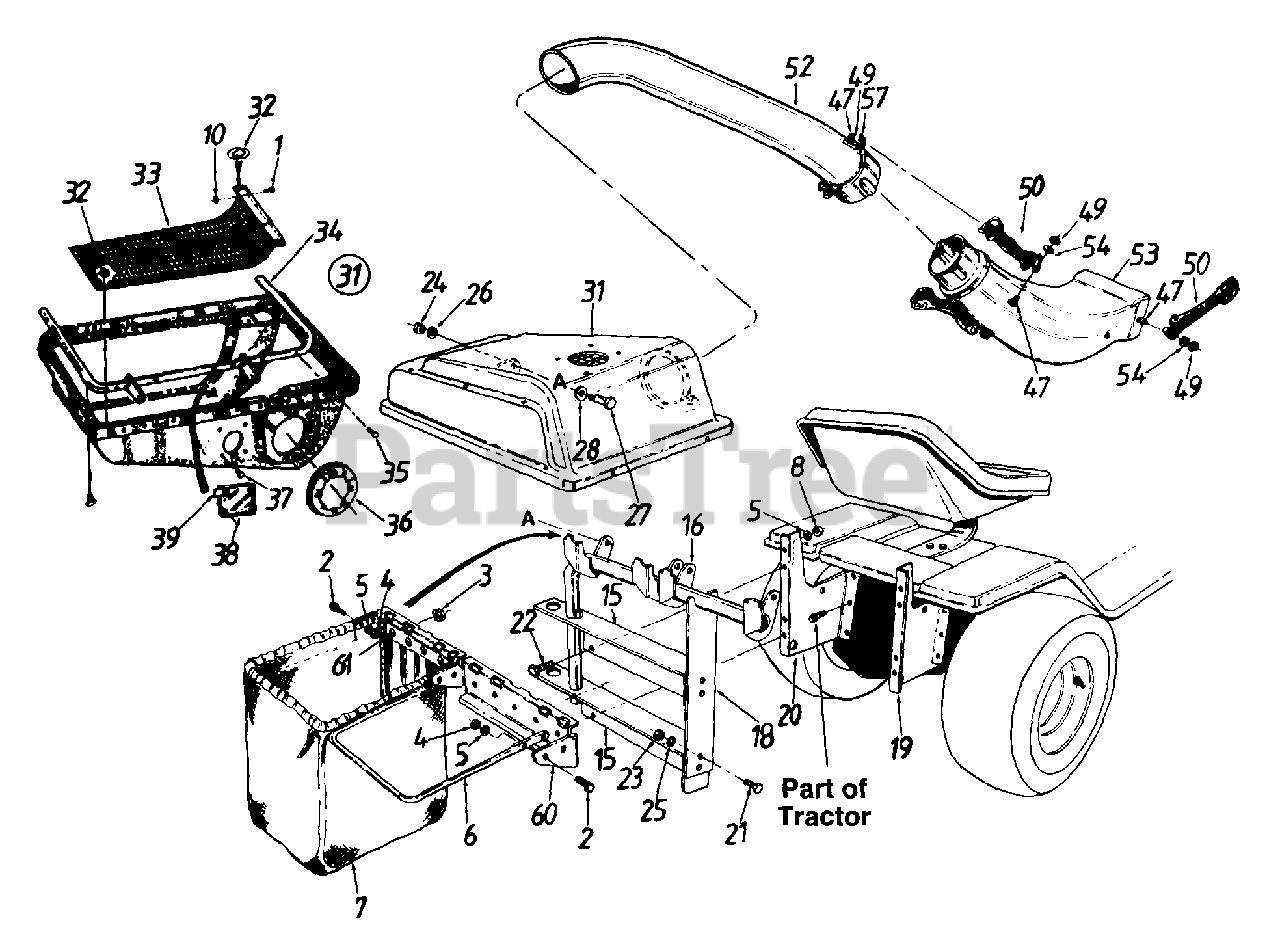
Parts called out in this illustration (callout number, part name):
1	Pop Rivet .188 Dia.
2	Hex Bolt 1/4-28 x .88"
3	Hex Sems Nut #10-24 Thd.
4	Hex Nut 1/4-28 Thd.
5	L-Wash. 1/4" I.D.
6	Catcher Bag Frame
7	Grass Catcher Bag
8	Hex Nut 1/4-20 Thd.
10	Flat Wash. 1/4" I.D.
15	Catcher Support Tube Mtg. Brkt.
16	Catcher Support Tube Ass'y.
18	Catcher Latch and Support Brkt.
19	Grass Catcher Support Brkt.- R H.
20	Grass Catcher Support Brkt.- L.H.
21	Hex Bolt 5/16-18 x .75"
22	Hex Bolt 1/4-20 x .62" Lg.- Grade 5
23	Hex Nut 5/16-18 Thd.
24	Hex Nut 3/8-16 Thd.
25	L-Wash. 5/16" I.D.
26	L-Wash. 3/8" I.D.
27	Shld. Bolt 3/8-16 x .50" Dia.
28	Bell-Wash. .505" I.D. x 1.0" O.D.
31	Grass Catcher Cover Ass'y. (063)
31	Grass Catcher Cover Ass'y. (103)
32	Twist Fastener
35	Hex AB-Tap Scr. 1/4 x .62"
36	Seal - 7" (063)
36	Seal - 8" (103)
37	Truss B-Tap Scr. #10 x .5" Lg.
38	Plastic Plate
39	Speed Nut
47	Hex Bolt 1/4-20 x .625"
49	Hex Ins. L-Nut 1/4-20 Thd.
50	Retainer Strap Ass'y.
52	Catcher Tube (063)
52	Catcher Tube (103)
53	Discharge Chute (063)
53	Discharge Chute (103)
54	L-Wash. .27" I.D.
57	Retainer Hook Brkt.
60	Bag Frame Hanger Brkt.
61	Truss Mach. Scr. #10-24 x .5"
